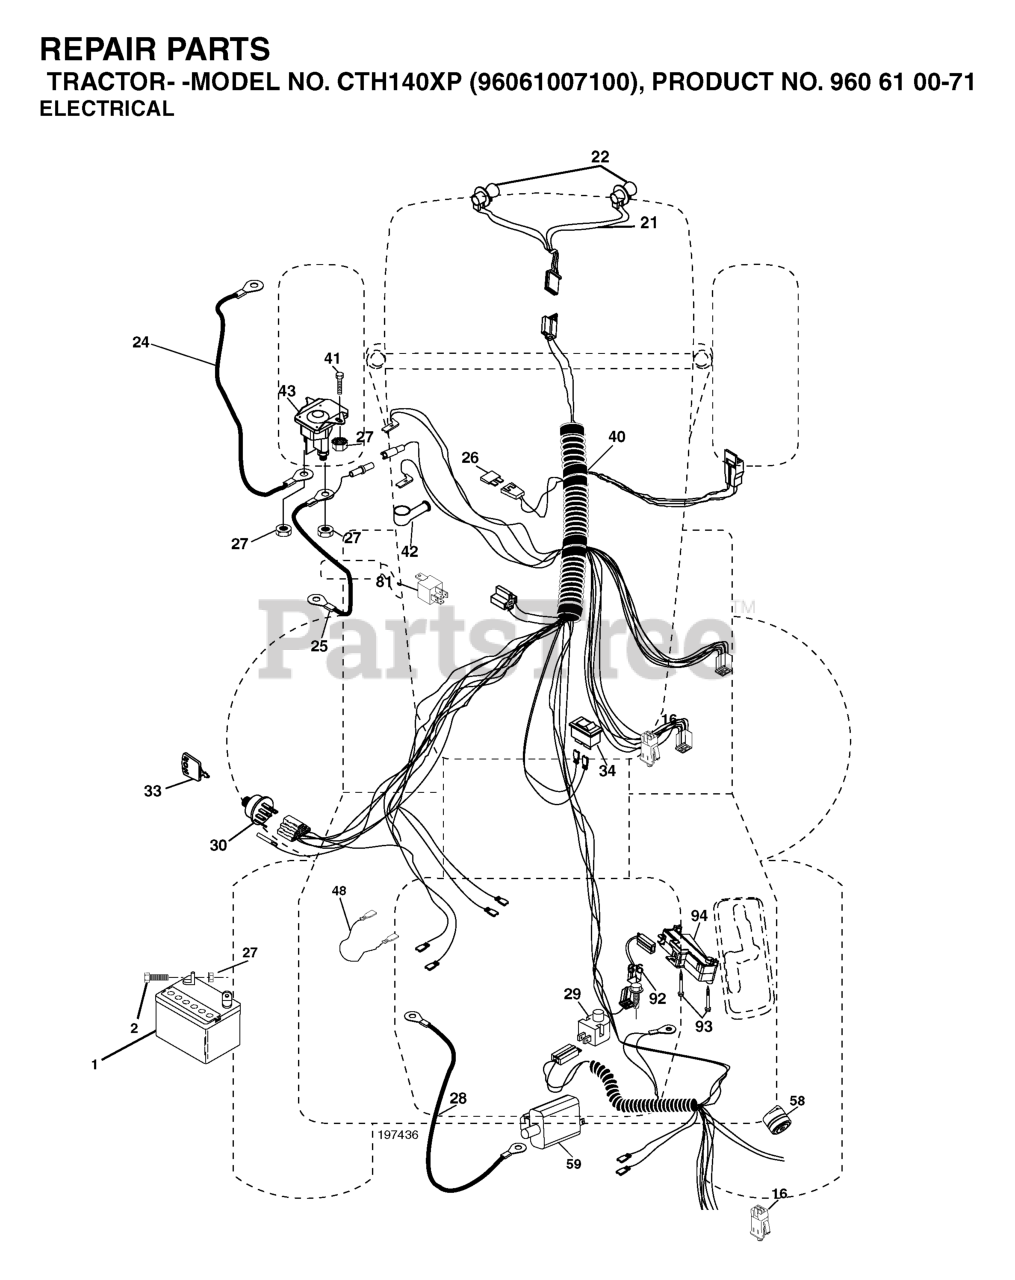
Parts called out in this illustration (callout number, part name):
1	BATTERY 12V .35 AMP
2	BOLT.HEX.1/4.X.3/4.DICHROMATE
16	SWITCH INTERLOOK PUSH-IN
21	HARNESS.W/LIGHT SOCKET
24	BATTERY CABLE GT
25	CABLE BATTERY
26	FUSE 20AMP
27	NUT
28	CABLE GROUND
29	SWITCH.SEAT.DP W/RAMPS
30	SWITCH.IGN.DELTA.W.LGH.ROS
33	KEY MLD GEN DELTA
41	BOLT
42	TERMINAL COVER
43	SOLENOID.W/BRASS.PLUNGER
48	ADAPTER.AMMETER
58	BUZZER
59	.WITCH.FULL BAGGER.INDICATOR
81	RELAY.ASSY.T
92	HARNESS.PIGTAIL.CONSLE
93	SCREW.PLASTITE
94	MODULE.REVERSE.ROS
